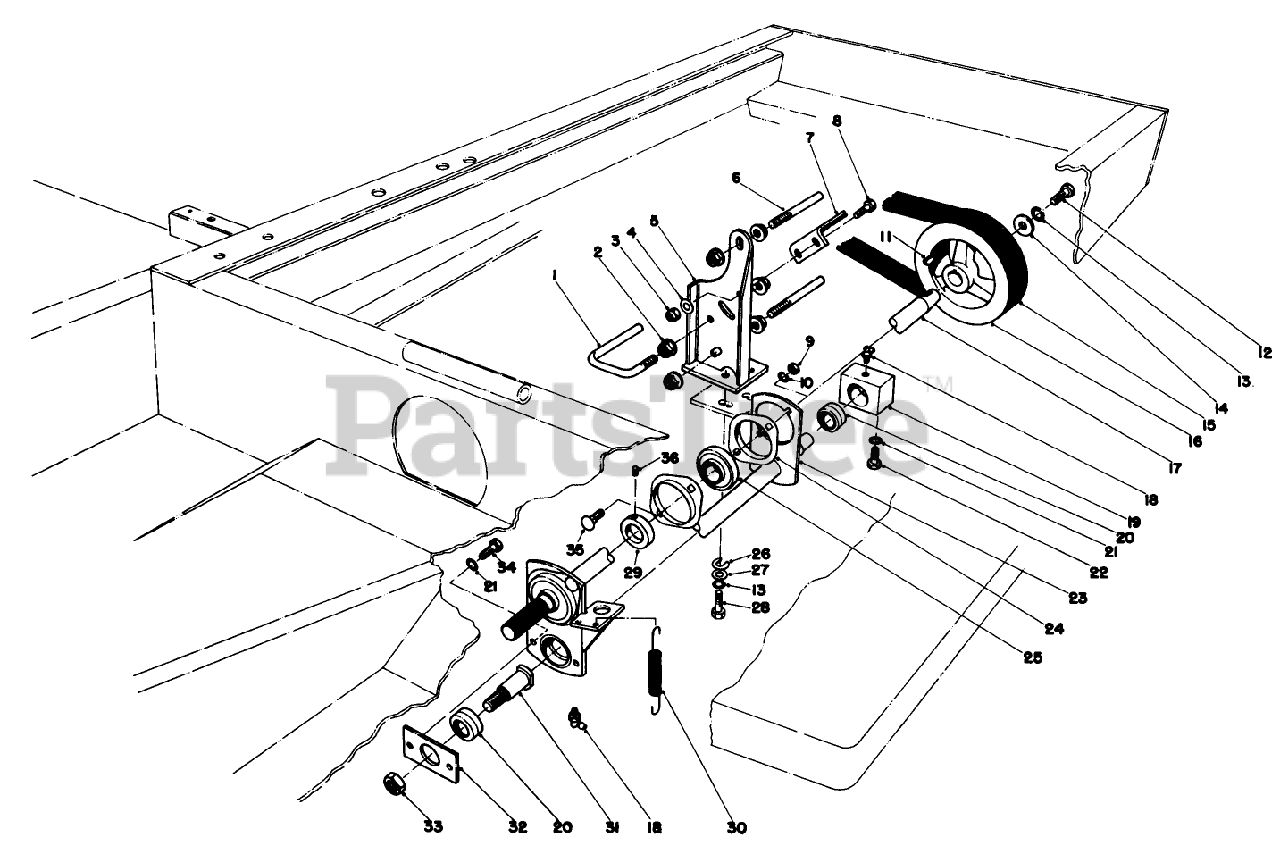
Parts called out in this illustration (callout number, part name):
1	LOWER BELT GUIDE
2	NUT-HHF, WHIZ
3	NUT-LOCK, NI
4	WASHER-PLAIN
6	UPPER BELT GUIDE
8	SCREW-HH
9	NUT-HEX
10	SCREW-HH
11	KEY-WOODRUFF
12	SCREW-HH
13	WASHER-LOCK
14	WASHER-FLAT
15	V-BELT
18	FITTING-GREASE, 90 DEG
20	BEARING
21	SCREW-HH
22	SCREW-HH
24	FLANGE
25	BEARING
26	SPECIAL WASHER
27	WASHER-FLAT
28	SCREW-HH
29	COLLAR-LOCK, BEARING
31	BEARING STUD
32	BRG RETAINER
33	NUT-LOCK, NI
34	SCREW-HH
35	SCREW-CARR
36	SCREW-SET, HSH
